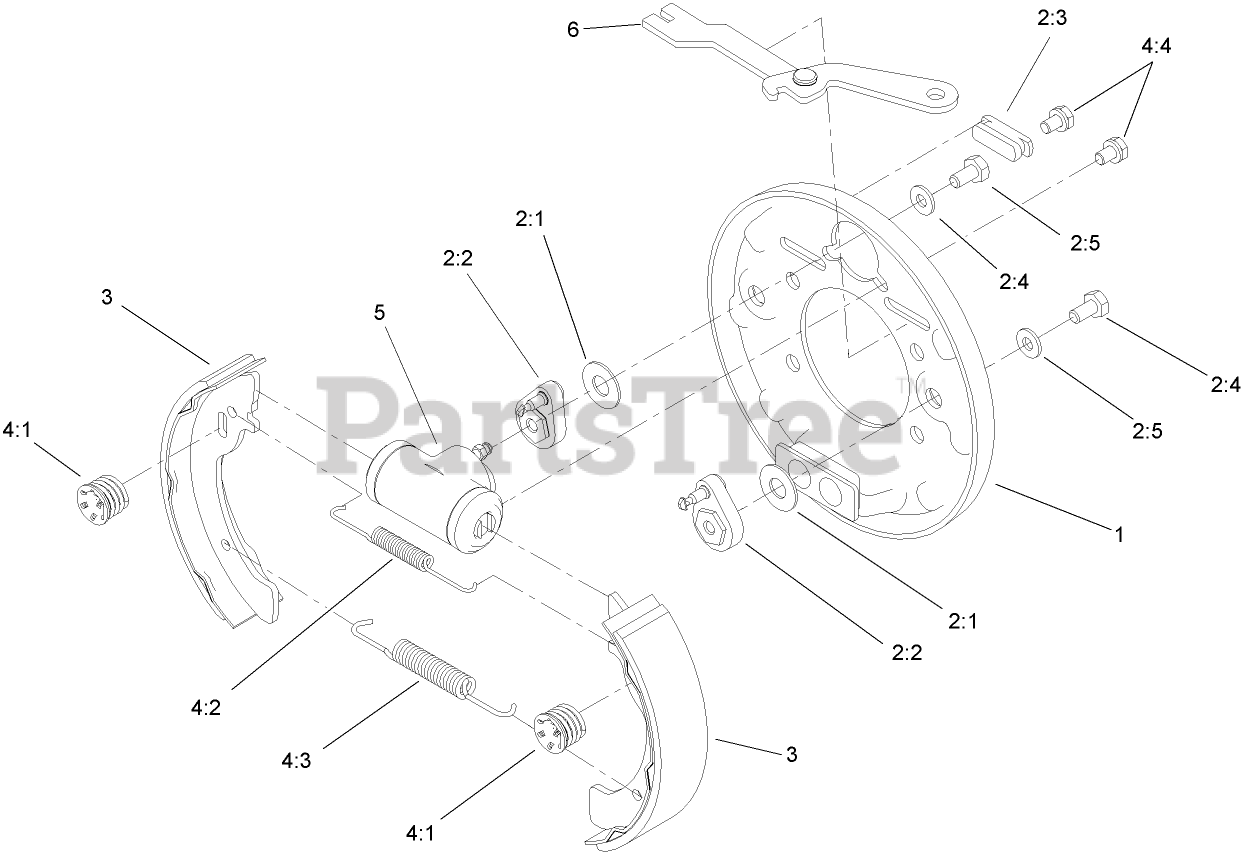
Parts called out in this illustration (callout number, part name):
1	BACKING PLATE ASM
2	ADJUSTER KIT
2:1	WASHER-BELLVILLE
2:2	ADJUSTER LEVER ASM
2:3	COVER-DUST
2:4	Washer
2:5	Bolt
3	SHOE AND LINING KIT
4	HARDWARE KIT
4:1	SHOE HOLD DOWN SPRING ASM
4:2	SPRING-UPPER
4:3	SPRING-LOWER
4:4	Loose Parts Package
5	WHEEL CYLINDER ASM
6	LH PARK BRAKE LEVER ASM
